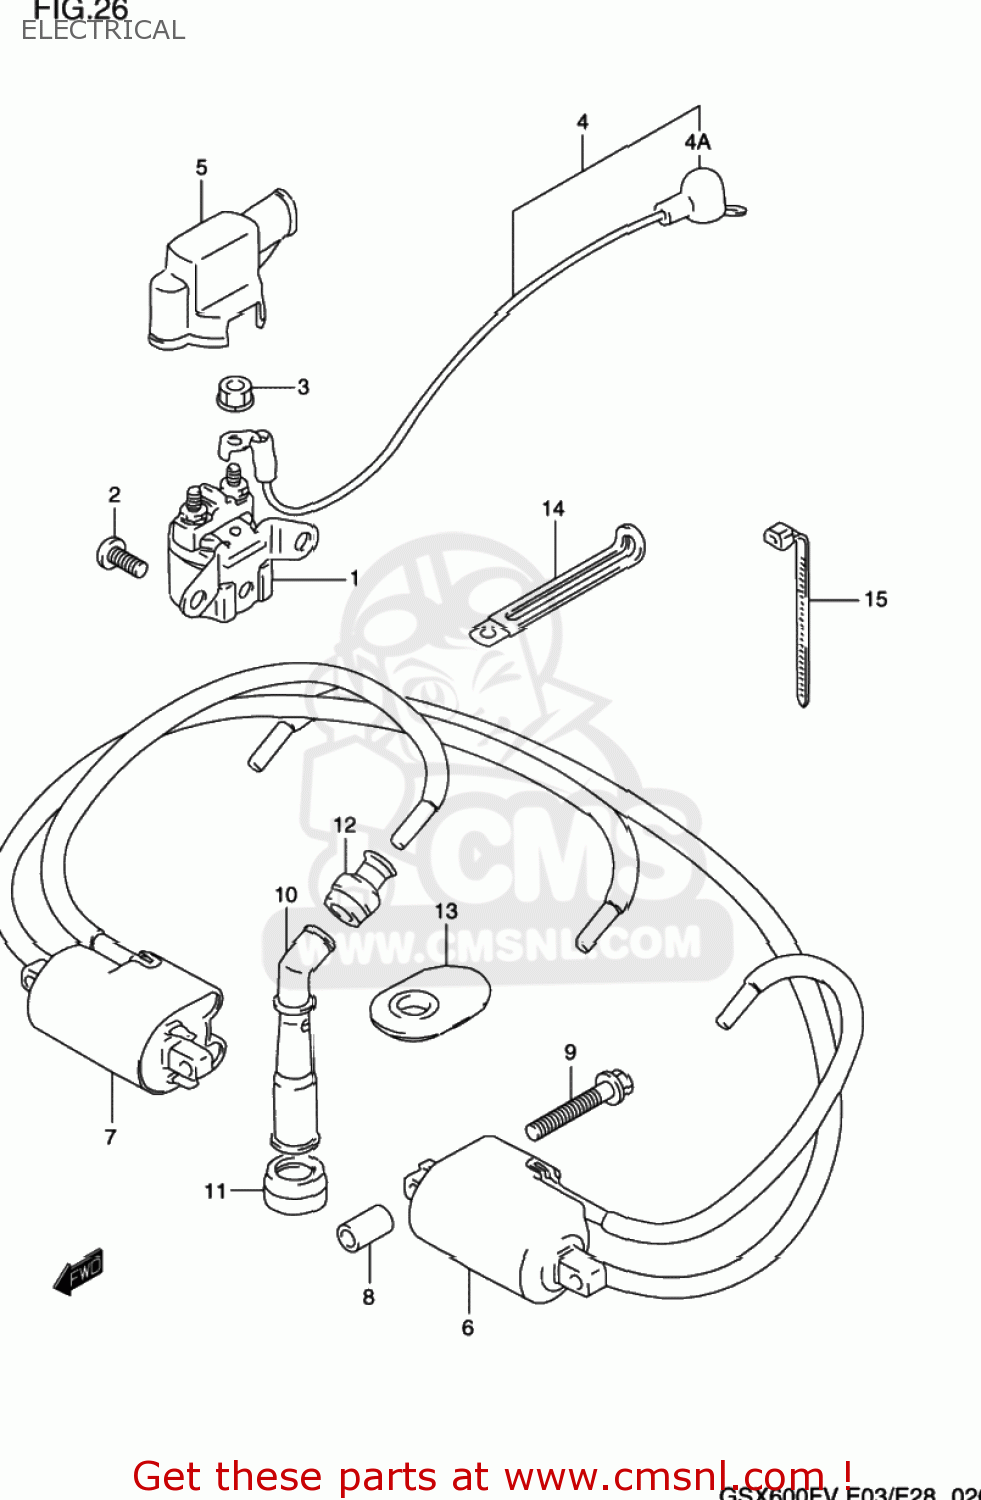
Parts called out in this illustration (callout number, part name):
1	RELAY ASSY,STARTING MOTOR
2	SCREW
3	NUT
4	WIRE,STARTER MOTOR LEAD
4A	CAP,STARTER MOTOR LEAD
5	CAP,STARTER RELAY
6	COIL ASSEMBLY,IGNITION NO
7	COIL ASSEMBLY,IGNITION NO
8	SPACER(6.2X12X16)
9	BOLT (6X45)
10	CAP,SPARK PLUG
11	SEAL,SPARK PLUG CAP
12	SEAL,HIGH TENSION CORD
13	COVER,SPARK PLUG CAP
14	CLAMP(L:65)
15	CLAMP L:165
